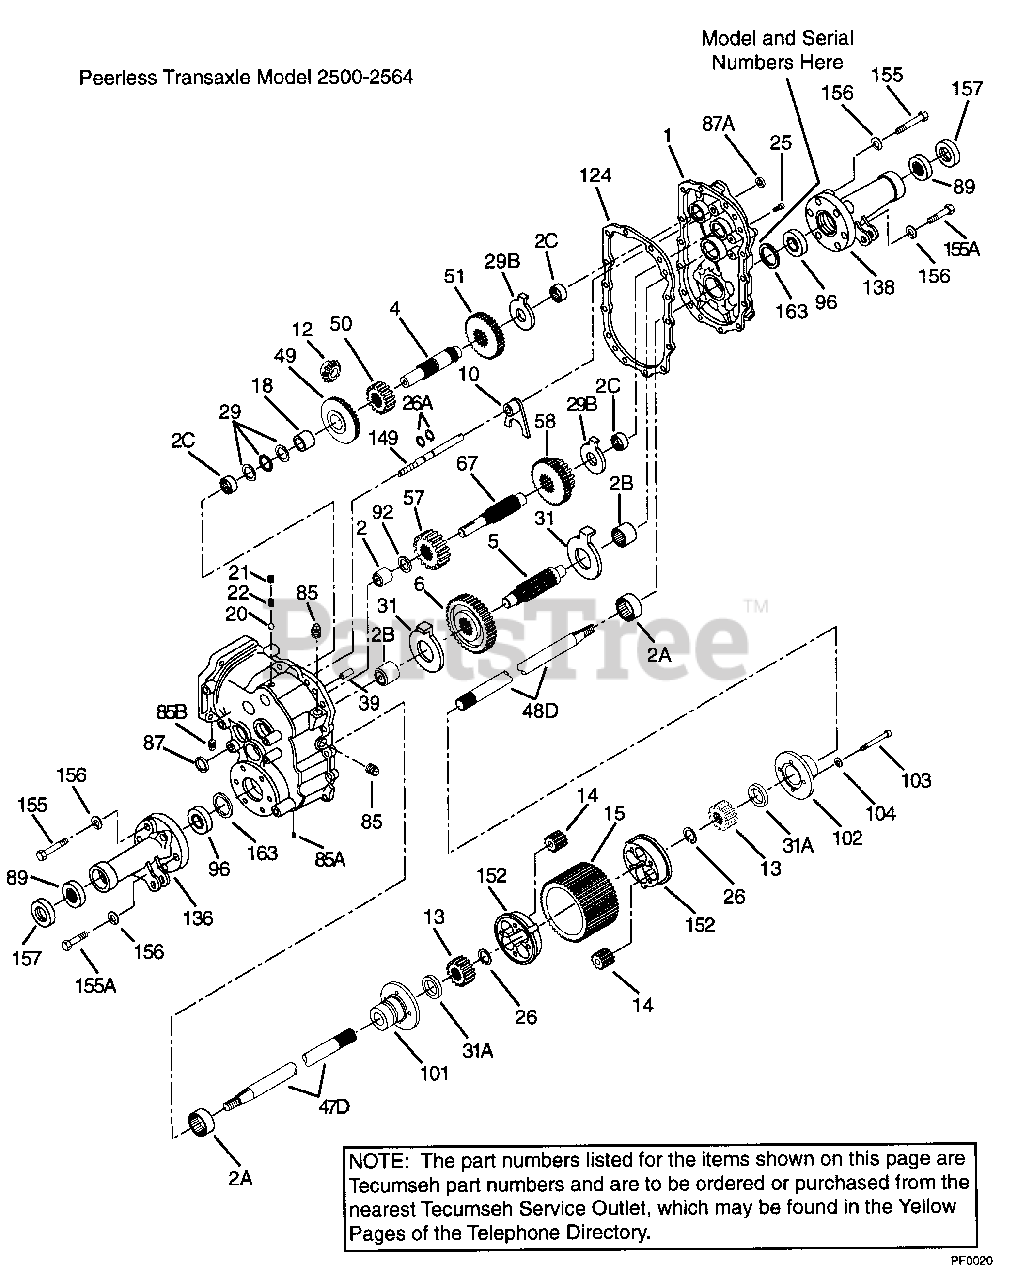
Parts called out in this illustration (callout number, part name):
1	Transaxle Cover(Incl. 2A, 2B & 2C)
2	Needle Bearing 1" ID
2A	Needle Bearing 2" ID
2B	Needle Bearing 1-1/4" ID
2C	Needle Bearing 1" ID
3	Transaxle Case(Incl. 2, 2A, 2B, 2C & 85B)
4	Countershaft
5	Output Shaft(13 teeth)
6	Spur Gear
10	Shift Fork
12	Bevel Pinion(13 teeth-steel)
13	Side Gear
14	Spur Pinion(10 teeth-steel)
15	Ring Gear
20	Ball 3/16" dia.
21	SetScrew 1/4-20 x 1/2"
22	Spring Detent
24	Thrust Bearing
25	Screw 5/16-18
26	Retaining Ring
26A	Ext. Retaining Ring .406
29	Thrust Washer
29B	Thrust Washer
31	Thrust Washer
31A	Thrust Washer(.060 thick)
39	Dowel Pin
47D	Axle(19-15/16" long)
48D	Axle(19-1/16" long)
49	Bevel Gear(30 teeth-steel)
50	Spur Gear(16 teeth-steel)
51	Spur Gear(23 teeth-steel)
57	Spur Gear(19 teeth-steel)
58	Shifter Spur Gear(20 & 27 teeth)
67	Shifter & Brake Shaft
85	PipePlug 3/8"
85A	Magnetic Drain Plug
85B	Plug 1/8-27
87	Oil Seal 1"
87A	Oil Seal 1/2"
89	Ball Bearing 1-1/8"
92	Thrust Washer
96	Thrust Bearing
101	Differential Carrier
102	Differential Carrier
103	Screw 3/8-16 x 3-5/16"
104	Lockwasher .343 ID
136	Axle Housing(11.2" long)
138	Axle Housing(11.2" long)
149	Shift Rod(High-Low)
152	Body Core
155	Screw 1/2-13 x 2-3/4"
155A	Screw 1/2-13 x 1-1/2"
156	Lockwasher
157	OilSeal 1-1/8"
163	Square Cut Ring
